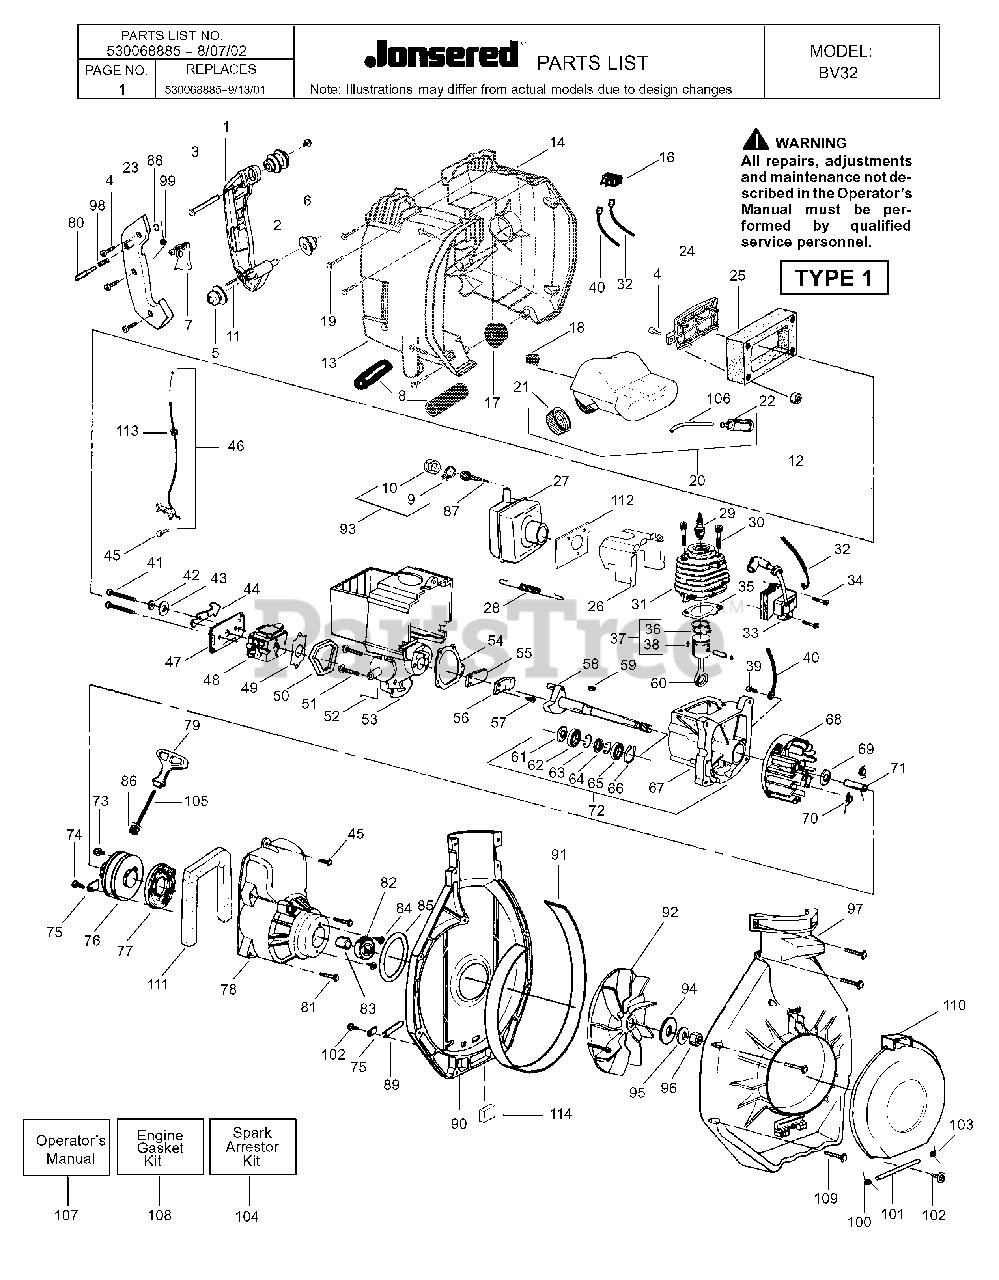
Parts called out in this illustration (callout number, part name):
1	HANDLE (BLACK)
3	SPACER-ISOLATOR
4	SCREW-10-14X5/8 PHIL.FI
5	ISOLATOR-HANDLE (REAR)
6	SCREW-10-24 X 3/8
9	CLAMP-SPARK ARRESTOR
11	HANDLE PIN
12	LOCKNUT - LINE LIMITER
17	ISOLATOR-ENGINE MOUNT
18	ISOLATOR-TANK
20	ASSY-FUEL TANK W/RETAIN
21	CAP ASSY W/ RETAINER
22	FUEL PICK-UP ASSY
23	ASSY-COVER & THROTTLE LOCK
25	AIR FILTER
26	AIR BAFFLE
28	SPRING-MUFFLER
30	SCREW 1/4-20 X 7/8
31	CYLINDER
33	IGNITION MODULE.
34	SCREW 8-32 X 3/4
35	GASKET-CYL W/ADHESIVE
36	RING-PISTON (HOOKED)
37	KIT-PISTON (32CC)
38	WRIST PIN RET.
39	SCREW(10-24 X 7/16 HEX
43	CHOKE SPACER
44	SHUTTER-CHOKE
45	SCREW 8-16 X 9/16 (PLAS
46	THROTTLE CABLE
47	PLATE-AIR FILTER MTG
48	CARB ASS'Y WT-141A
49	GASKET-CARB
50	SEAL-FOAM/REED BLOCK
51	SCREW 1/4-20 X 7/8 (TAP
52	WIRE-GROUND/STATIC
53	REED BLOCK/HEAT SHIELD
54	GASKET-REED BLOCK/C'CAS
55	VALVE-REED
56	REED STOP
58	ASSY-CRANKSHAFT
59	KEY-FLYWHEEL
60	ASS'Y-CONNECTING ROD
62	BEARING-R8 (INNER)
63	RING-RETAINING
64	SEAL-CRANKSHAFT
65	BEARING-R8 (OUTER)
66	RING-RETAINING (SHAFT)
67	ASSY-CRANKCASE
69	WASHER
70	SPRING STR DOG
72	ASSY-C'CASE & C'SHAFT
74	SCREW-10-16 X 1/2 HI-LO
77	STARTER SPRING
78	FAN HOUSING KIT
79	HANDLE-STARTER
80	BUTTON-THROTTLE LOCK
81	SCREW-10-24X1-3/8-TAPTI
85	O-RING SEAL
86	EYELET-FLANGE
87	SCREEN-SPARK ARRESTOR
88	C CLIP-THROTTLE LOCK
89	TUBE-ROPE RETAINER
90	HSG-BLOWER (UPPER) (BL)
91	BAND-BLOWER HSG
92	ASSY-IMPELLER
94	WASHER-IMPELLAR
95	WASHER CONICAL
97	BLOWER HOUSING ASSY - BLACK
98	SPRING-THROTTLE
99	SPRING-LEVER RETURN
100	SPRING-TORSION (RIGHT)
101	PIN-PIVOT
102	SCREW-10-16X1/2 HI-LO(S
103	SPRING-TORSION (LEFT)
104	SPARK ARRESTOR KIT
108	KIT-GASKET
109	SCREW
112	HEAT SHIELD/AIR DAM
113	GROMMET-CARB. BOX
530047885	DECAL LOWER HOUSING
